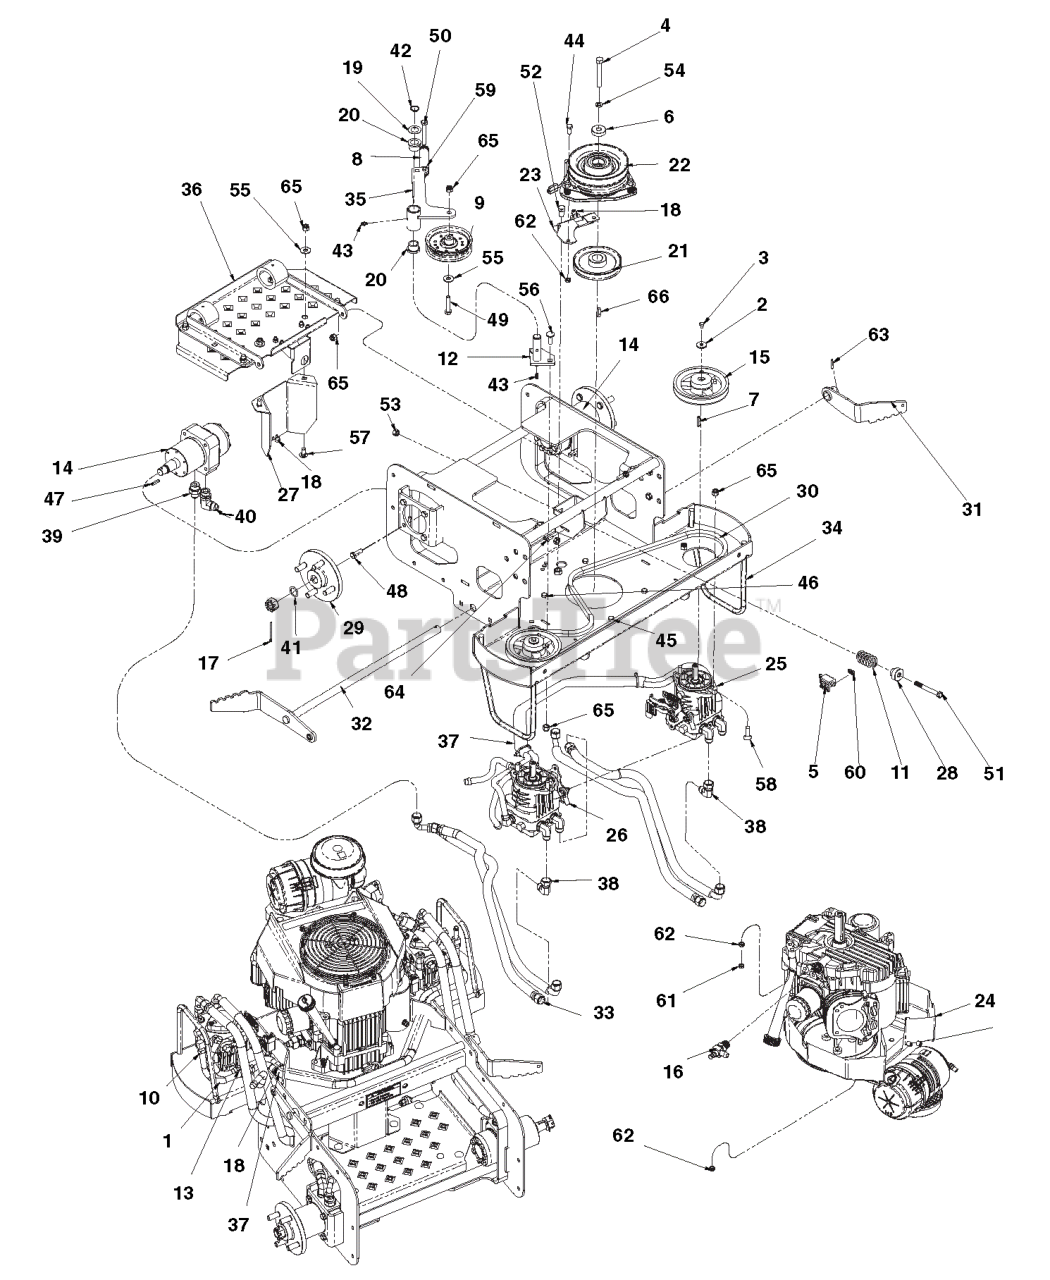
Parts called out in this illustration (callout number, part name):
1	HOSE, 3/8 SAE30R7 FUEL & OIL
2	WASHER, .250 WIDE HEAVY FLAT Y
3	BOLT, M6X1.00X10 HEX 8.8 Y
4	BOLT, 7/16-20X3.00 HEX 5 Y
5	SWITCH (N.0.)
6	SPACER, .468 X 1.38 X .375 Y
7	SHAFT KEY
8	SPRING, EXT .900X.135X4.50 Y
9	PULLEY, V-BELT4.00X.379 W/BRG
10	CLAMP, HOSE - 1/2" PINCH
11	SPRING, COM 1.22X.162X2.50 Y
12	WLDT, PIVOT IDLER MOUNT
13	FTG, TUN 3/8 HOSE
14	MOTOR, HYD WHEEL
15	ASSY, PUMP PULLEY W/SET SCREW
16	FITTING, OIL DRAIN #
17	PIN,.125X2.00 ZN COTTER 1010 #
18	CABLE TIE, .15 X 8.50
19	WSHR-FL-STL .750X1.250X.048 YZ
20	BRG, FLG .750X1.00X.750 BRNZ
21	PULLEY, V-BELT 4.78PD X 1.000
22	CLUTCH ASSY, OGURA# GT1A-HU02
23	PLATE, CLUTCH DOG
24	ENGINE, KAWASAKI 19HP FH580V
25	ASSEMBLY, HYD PUMP
26	ASSEMBLY, HYD PUMP
27	COVER, OPC
28	WASHER, SPRING Y
29	ASSY, REAR WHEEL HUB
30	BELT, HA 68.2 EL AMD OHR
31	WLDT, RH BRAKE ARM
32	WLDT, LH BRAKE
33	HOSE, HYD 1/2 X 26 1/2 EZFLEX
34	WLDT, FRAME 34 W/DECALS-BLACK
35	WLDT, IDLER PIVOT
36	ASSY, FOOT PLATE
37	ABRASION SLEEVE 3 FEET S/O
38	ADAPTER, 3/4 FESW X 3/4MJICX90
39	FTG, ADP 3/4-16MJICX7/8-14MOR
40	FTG, 7/8ORB X 3/4JIC X 90
41	SHIM, .020X.787X1.102
42	SNAP RING, .750 X .042 EXT
43	FTG, 1/4-28 STRGT GREASE ZERK
44	BOLT, 5/16-18X.750 HEX 5 Y
45	BOLT, 5/16-18X1.50 HEX 5 Y
46	BOLT, 5/16-18X1.75 HEX 5 Y
47	KEY, WOODRUFF 3/16 X 3/4
48	BOLT, 3/8-16X1.00 HEX 5 Y
49	BOLT, 3/8-16X1.75 HEX 5 Y
50	BOLT, 3/8-16X2.50 HEX 5 Y
51	BOLT, 3/8-16X3.25 HEX 5 Y
52	BOLT, 7/16-14X.750 HEX 5 Y
53	NUT, 3/8-16 STD HEX GR5 Y
54	WASHER, .375 MED SPRG LOCK Y
55	WASHER, .375 REG FLAT Y
56	BOLT, 3/8-16X1.00 CRG 5 Y
57	BOLT, 3/8-16X.750 CRG 5 LN Y
58	BOLT, 3/8-16X1.25 CRG 5 Y
59	NUT, 3/8-16 JAM GR5 Y
60	LOCKNUT, 10-24 NYLOC Y
61	NUT, 5/16-18 JAM GR5 Y
62	LOCKNUT, 5/16-18 NYLOC Y
63	PIN, ROL .156 X 1.00
64	SCREW, 10-24X.625 PAN PHL MACY
65	LOCKNUT, 3/8-16 NYLOC Y
66	KEY, .250 X .250 X .995 TPR
